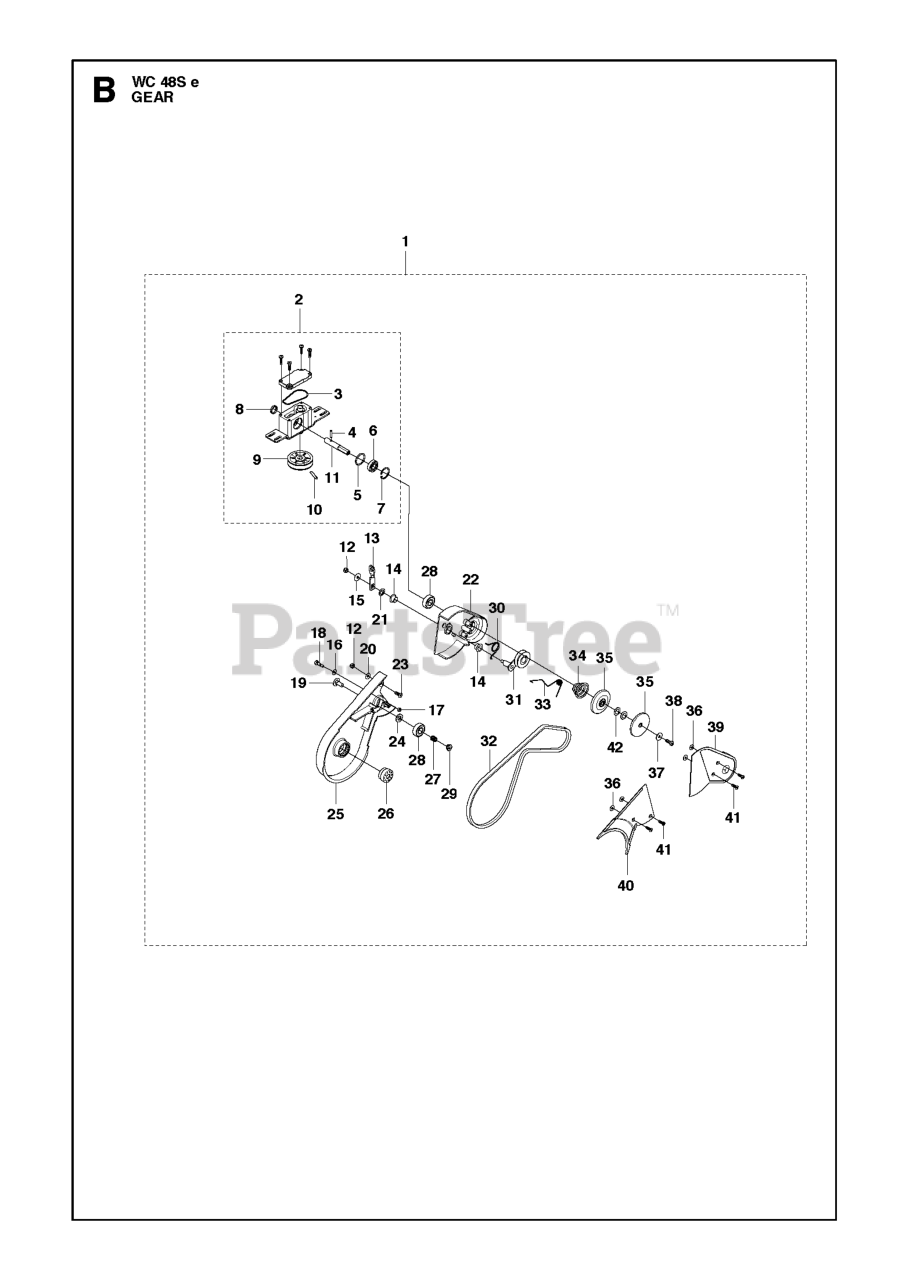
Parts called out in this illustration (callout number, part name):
6	BALL BEARING
12	NUT FLANGE - M6
15	WASHER 19X6X1
